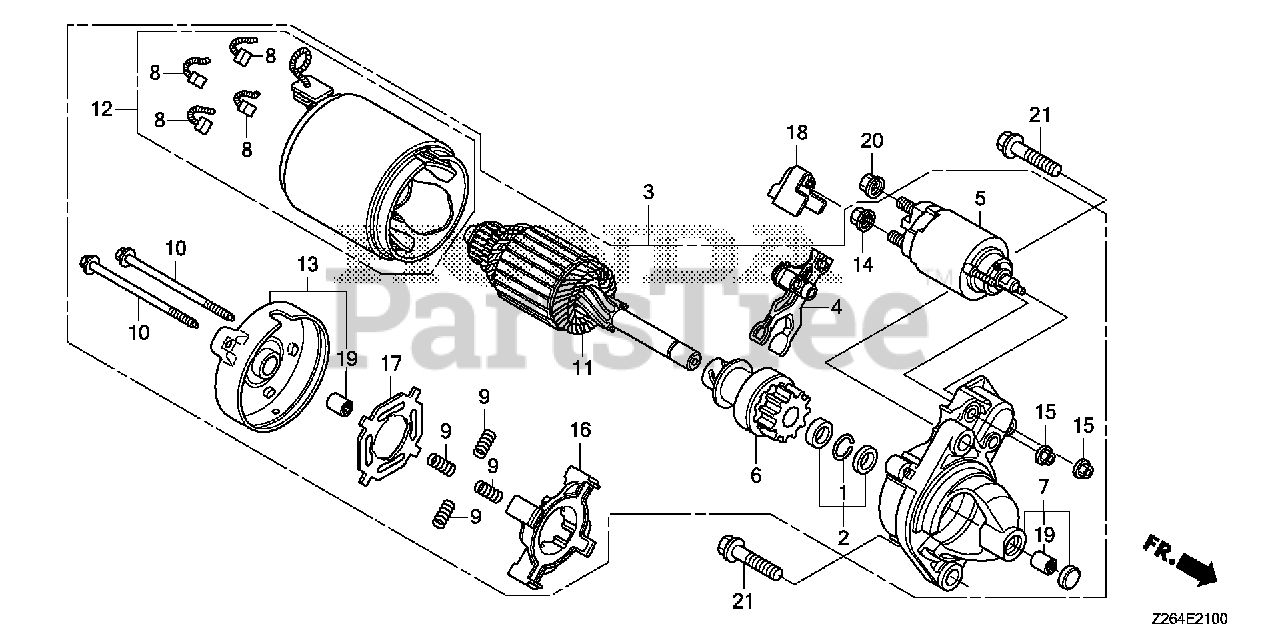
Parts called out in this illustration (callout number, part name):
1	RING, SNAP (DENSO)
2	COLLAR SET, CLUTCH STOP
3	STARTER MOTOR ASSY.
4	LEVER, PINION DRIVE
5	SWITCH ASSY., MAGNET
6	CLUTCH, OVERRUNNING
7	HOUSING, DRIVE SIDE
8	BRUSH
9	SPRING, BRUSH
10	BOLT, THROUGH
12	YOKE
13	FRAME, COMMUTATOR END
14	NUT, HEX. (8MM)
15	NUT, FLANGE (5MM)
16	HOLDER, BRUSH
17	INSULATOR, BRUSH HOLDER
18	COVER, TERMINAL
19	BEARING A
20	NUT-WASHER (8MM)
21	BOLT, FLANGE (10X40)
